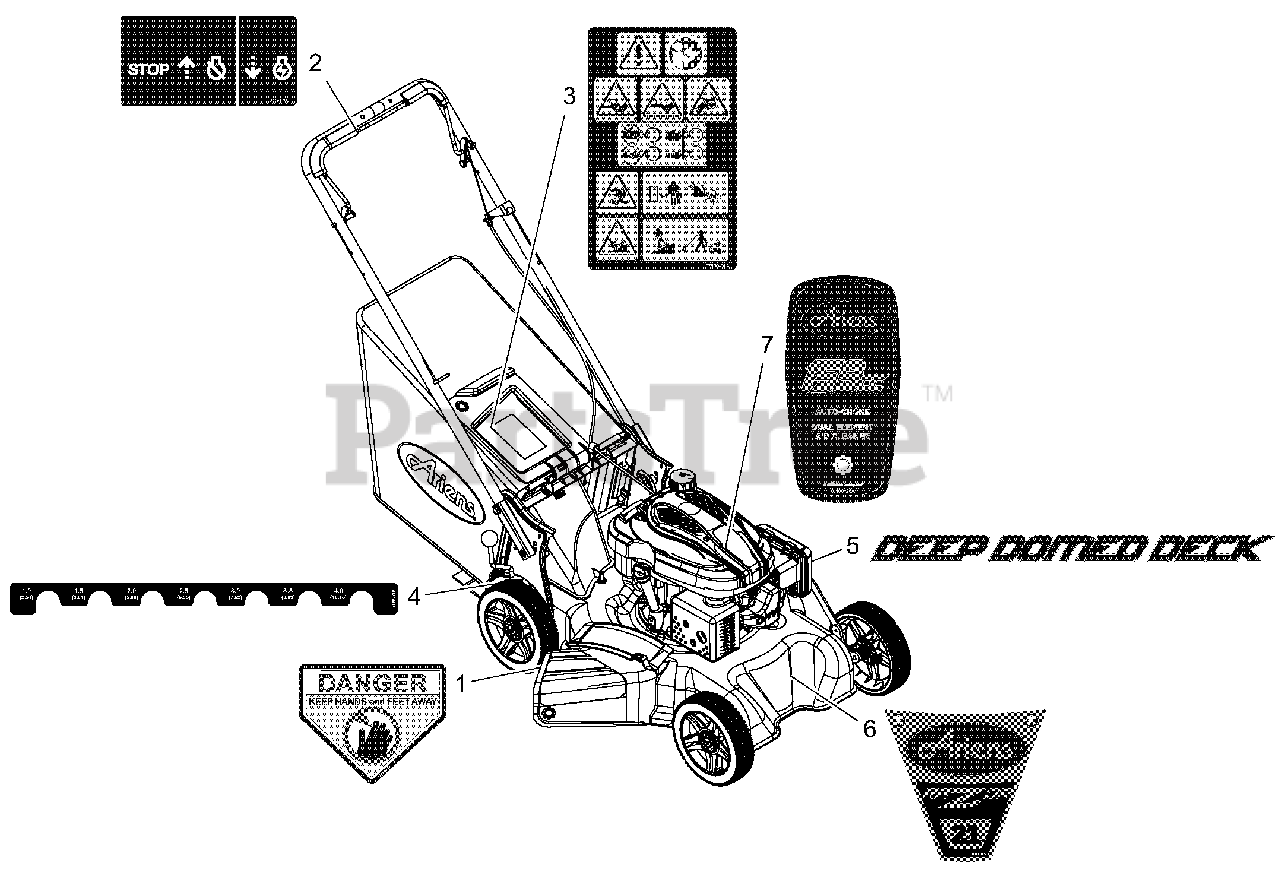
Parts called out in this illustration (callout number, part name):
1	DECAL, DANGER
2	DECAL - ENGINE CONTROL
3	DECAL,MAIN SAFETY_WAW LM
4	DECAL, HOC
5	DECAL, DEEP DOME DECK
6	DECAL, ARIENS RAZOR STYLE
7	DECAL, ENGINE STYLE - ARIENS
